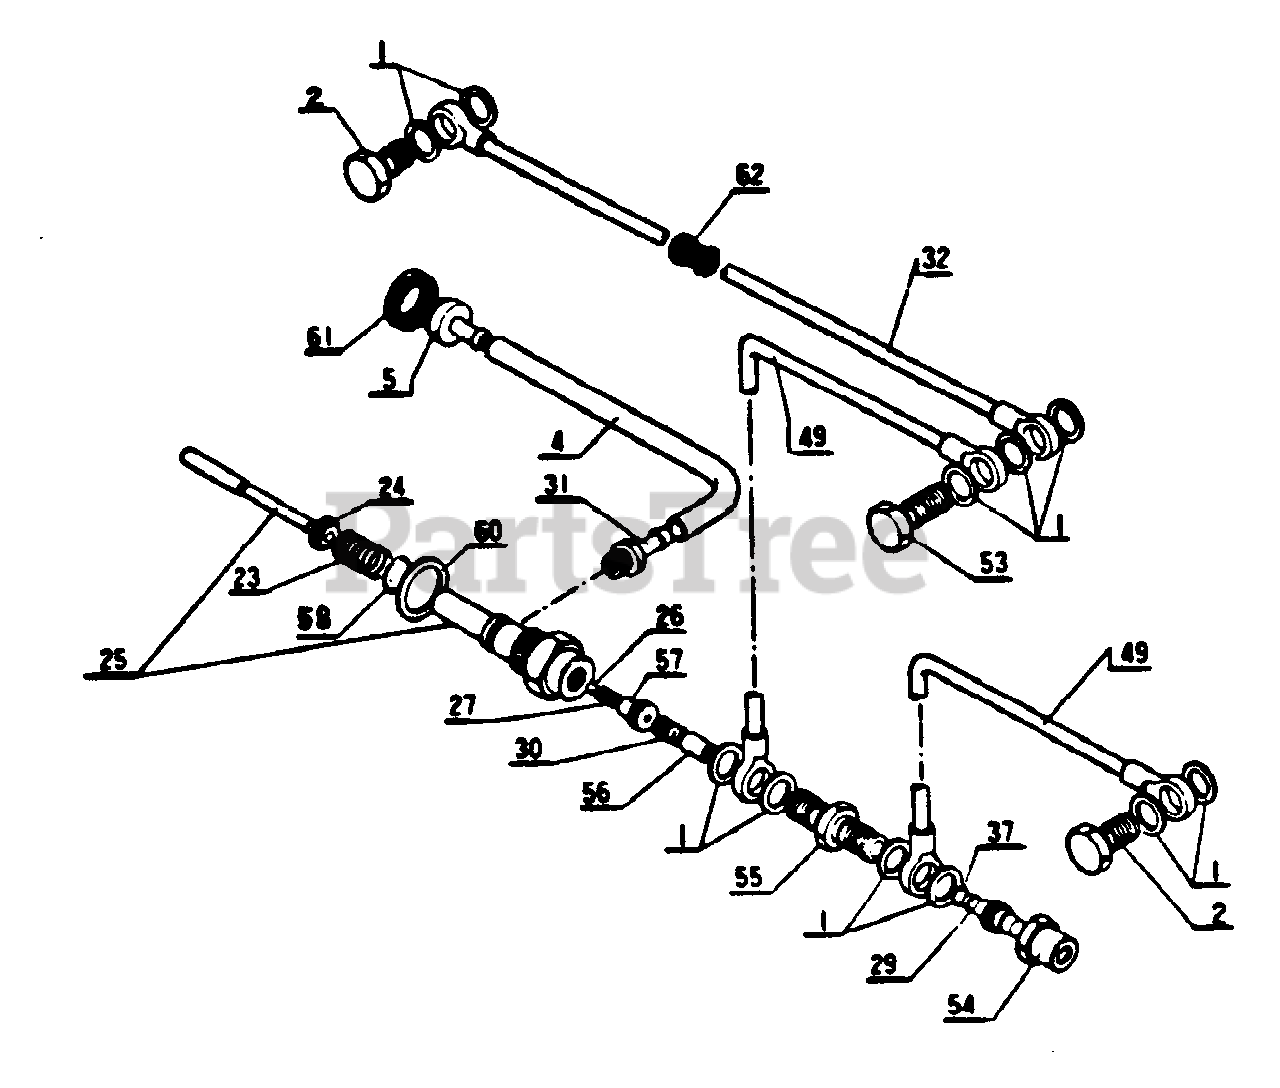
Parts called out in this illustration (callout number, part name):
1	GASKET
2	HOLDING BOLT
4	PIPE, OIL - INNER
5	FILTER, OIL
23	SPRING
24	SPRING CASE
25	CYLINDER, OIL
26	VALVE, BALL
27	SPRING, VALVE
29	SCREW, ADJUST
30	SPRING
31	NIPPLE
32	PIPE, OIL
37	O-RING
49	PIPE, OIL
53	HOLDING BOLT
54	NUT, ADJUST
55	PUMP ADJUSTER
56	PUMP SPACER
57	SEAT, VALVE
58	O-RING
60	PACKING
61	OIL FILTER COVER
